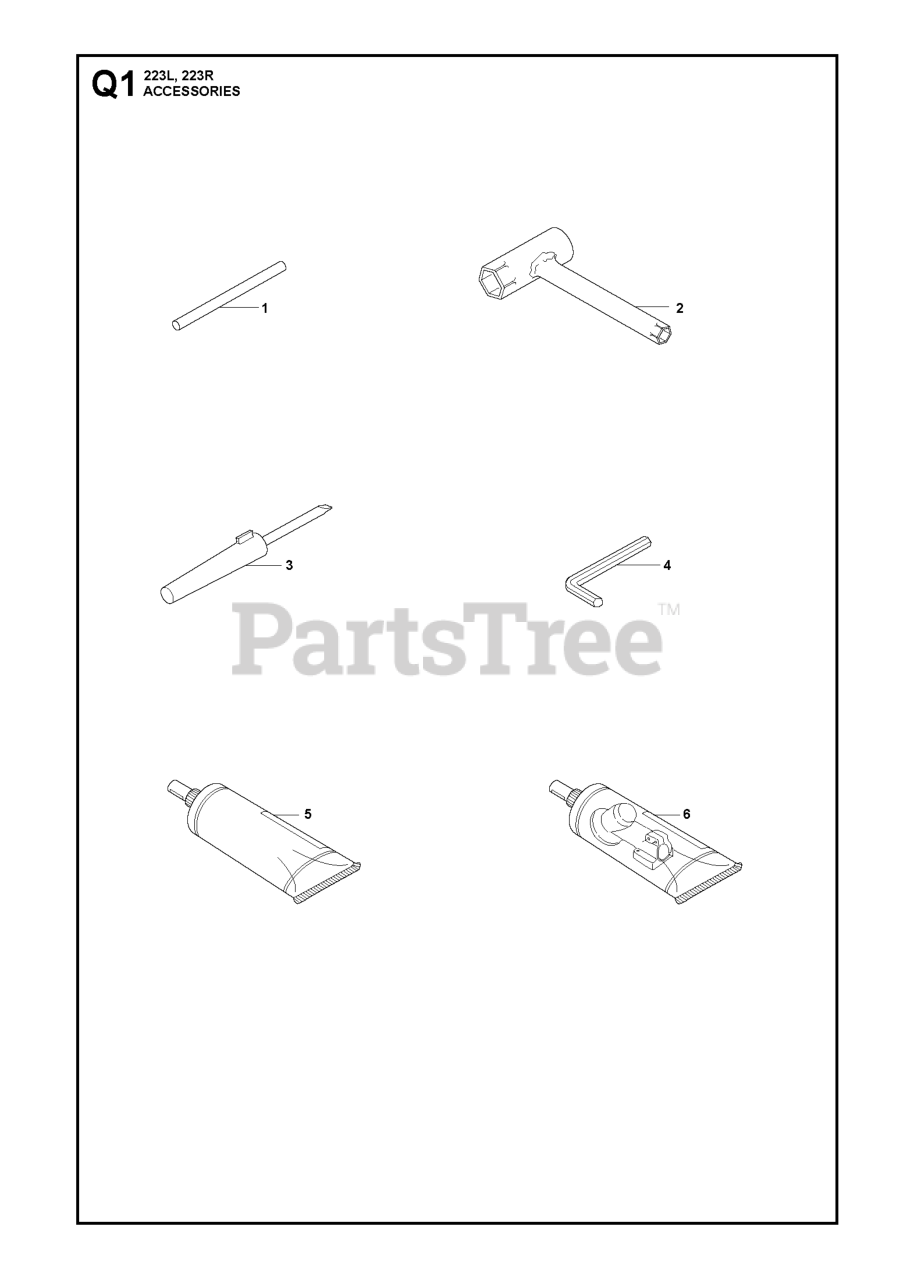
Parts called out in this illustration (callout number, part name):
1	LOCKING PIN
2	COMBI WRENCH
3	SCREWDRIVER
4	L-KEY WRENCH
5	DRIVE SHAFT GREASE (200 G)
6	BEVEL GEAR GREASE
